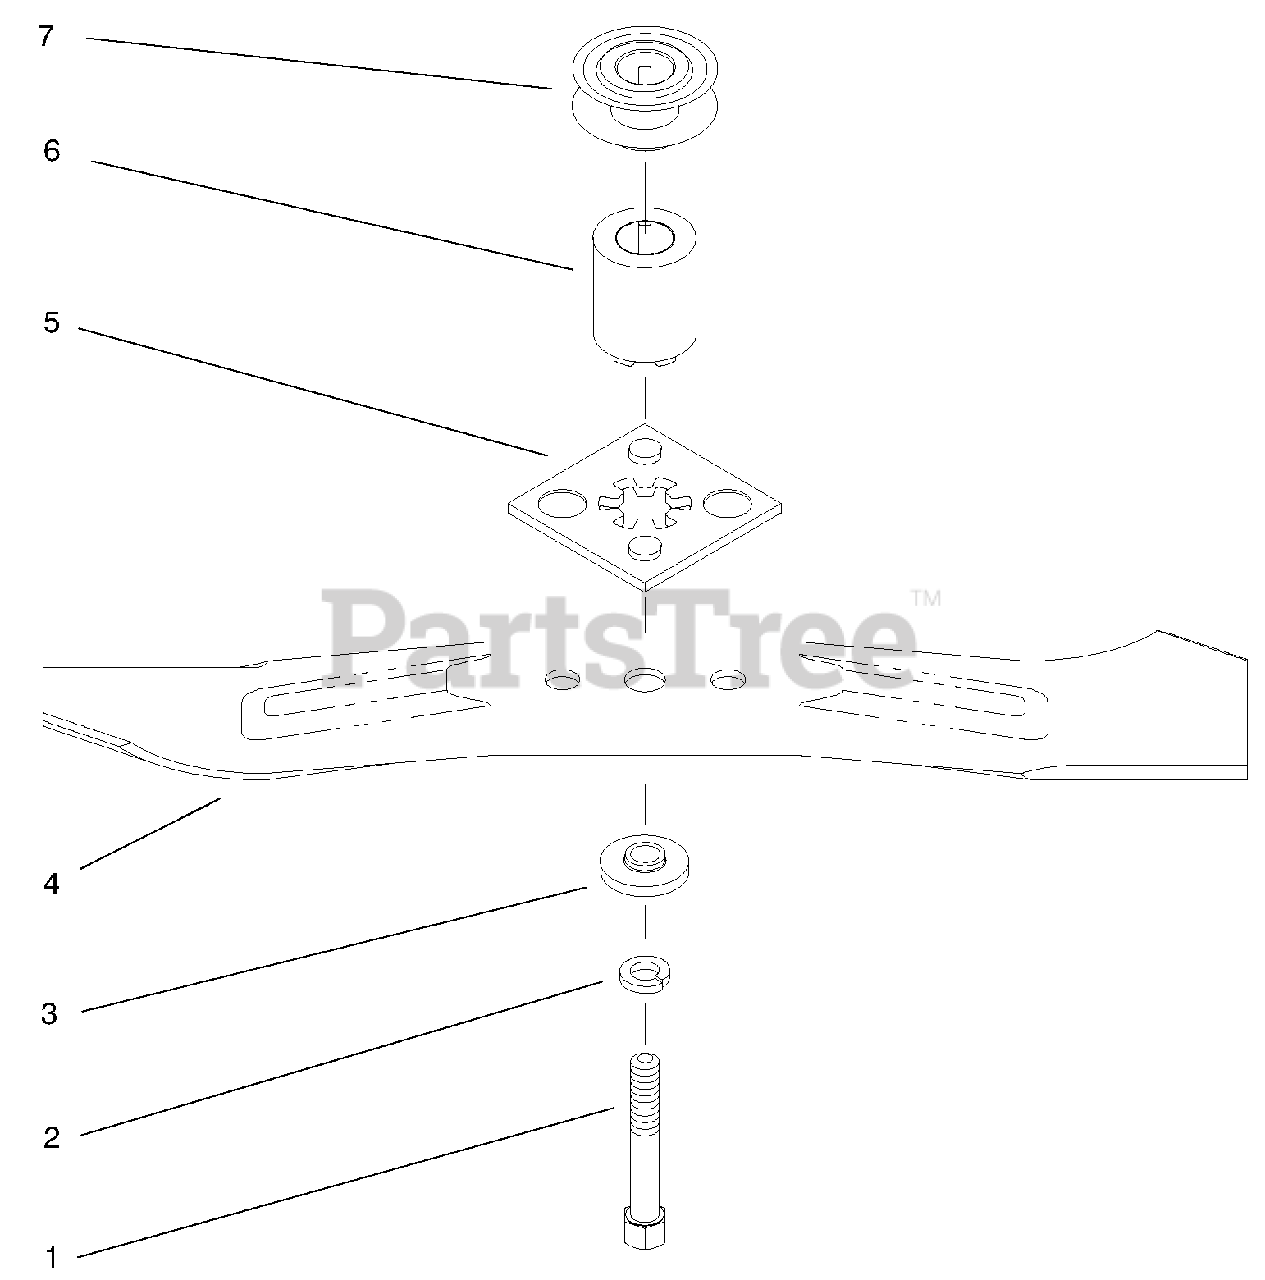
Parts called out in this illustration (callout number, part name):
1	SCREW-BLADE
2	WASHER-LOCK
3	SPACER-BLADE
4	Blade
5	PLATE DR
7	PULLEY - DRIVER
